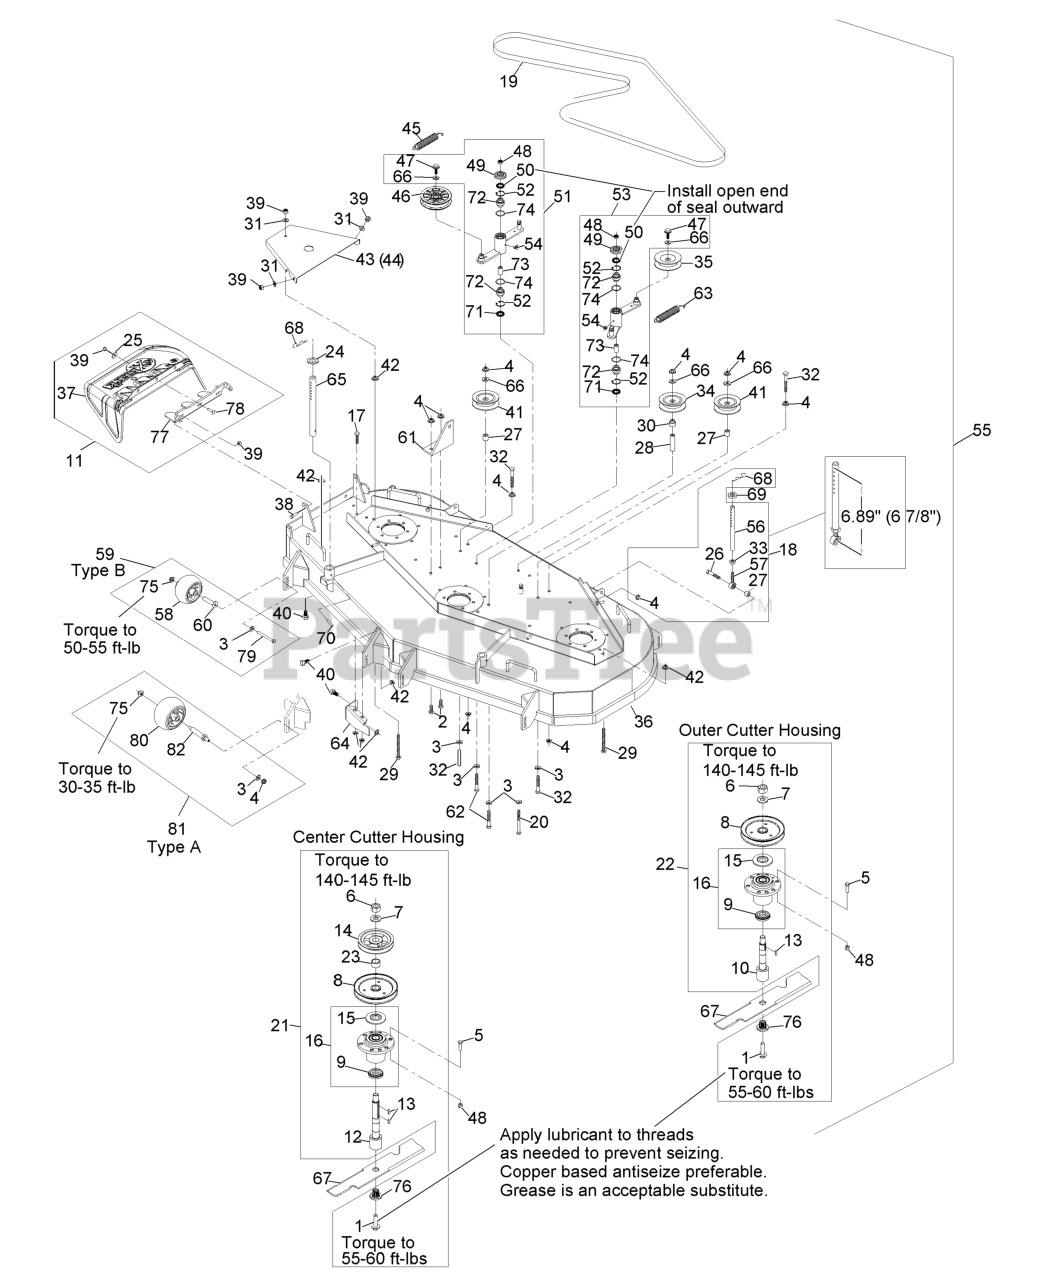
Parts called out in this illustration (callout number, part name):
1	SCREW,SEMS 1/2-20 X 2.19
2	SCREW-HH
3	WASHER-BELLEVILLE
4	NUT-HHF, WHIZ
5	SCREW-HH
8	SHEAVE,BLADE DRIVE 6.30
9	SPACER-GUARD, BOTTOM
10	KIT, SPLINED SPINDLE 103-
11	ASM,FMD DISCHARGE CHUTE
12	KIT, SPLINED SPINDLE 103-
14	SHEAVE,BLADE DRIVE
15	GUARD-BEARING, TOP
16	KIT, CUTTER HOUSING
17	SCREW-HH
18	KIT,SUPPORT LINK W/PIN
19	BELT,MULE DRIVE
20	SCREW-HH
21	ASM, CUTTER HSG FMD604CTR
22	ASM, CUTTER HSG COMPLETE
23	SPACER,TUBE
24	SPACER-DECK SUPPORT
25	WASHER-FLAT
26	SCREW-HH
28	SPACER-ANCHOR, CLUTCH
29	BOLT,TAP HH
30	BUSHING,IDLER
31	WASHER-FLAT
32	BOLT-CARR
33	NUT-HJ
34	PULLEY-IDLER
35	PULLEY-IDLER
36	ASM, DECK W/ DECALS FMD60
37	CHUTE,DISCHARGE
38	SCREW-HH
39	NUT-LOCK, NI
40	SCREW-HH
41	IDLER,PULLEY
43	SHIELD,BELT RH
44	SHIELD,BELT LH
45	SPRING-EXTENSION
46	PULLEY-IDLER, FLAT
47	SCREW-HHF
48	NUT-LOCK, NI
49	GUARD-TOP
50	SEAL-LIP, SINGLE
51	KIT, IDLER ARM W/BEARINGS
52	RING-SNAP
53	KIT, IDLER ARM W/BEARINGS
54	FITTING-GREASE, 90 DEG
55	Complete Deck Assy
56	LINK,SUPPORT
57	BALLJOINT
58	ROLLER-SCALP, ANTI
59	KIT, ANTI-SCALP ROLLER
60	AXLE, ROLLER
61	BRACKET,SPRING ANCHOR
62	SCREW-HH
63	SPRING-EXTENSION
64	BAFFLE,DISCHARGE
65	ROD,DECK SUPPORT
66	WASHER-FLAT
68	PIN,HAIR COTTER
71	SEAL-LIP, DOUBLE
72	BEARING-SPHERICAL
73	BUSHING-LEVER, LIFT
75	Nut-Nyloc 3/8-16 Flg
76	BUSHING,SPLINED
77	BRACKET, DISCHARGE CHUTE
78	SCREW-CARR
79	SCREW-HH 3/8-16 X 3 3/4 GR 8
80	ROLLER-SCALP, ANTI
